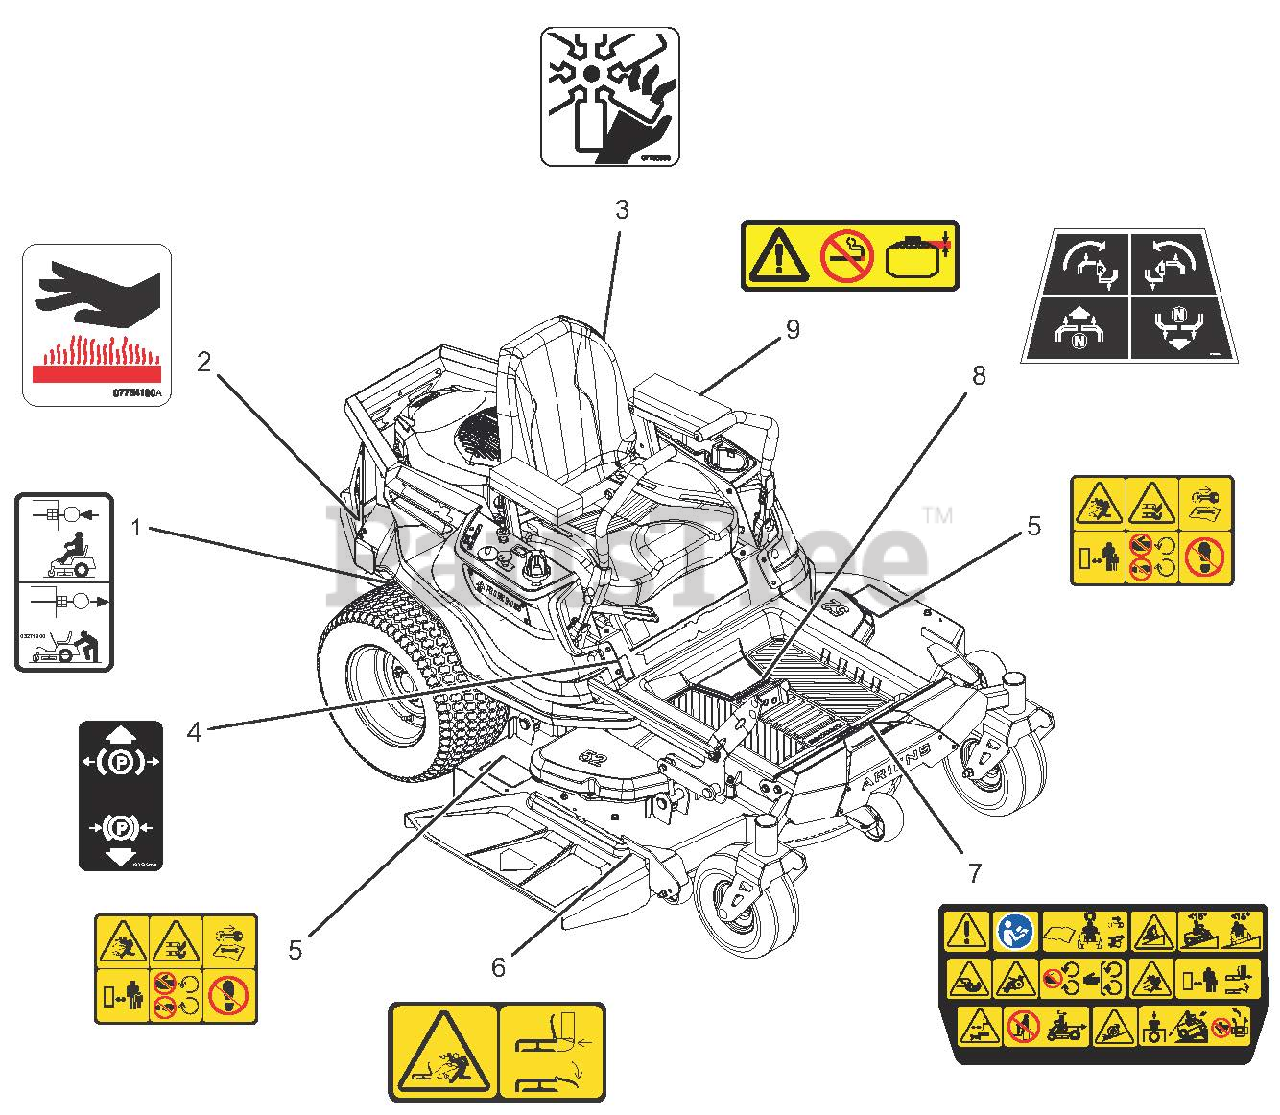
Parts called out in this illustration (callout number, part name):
1	DECAL, TRANSMISSION DISCONNECT
2	DECAL, HOT SURFACE
3	DECAL, DANGER FAN
4	DECAL, PARKING BRAKE LEVER
5	DECAL, SAFETY - MOWER DECK
6	DECAL, SAFETY - DECK GUARDING
7	DECAL, MAIN SAFETY
8	DECAL, STEERING
9	DECAL, FUEL WARNING
